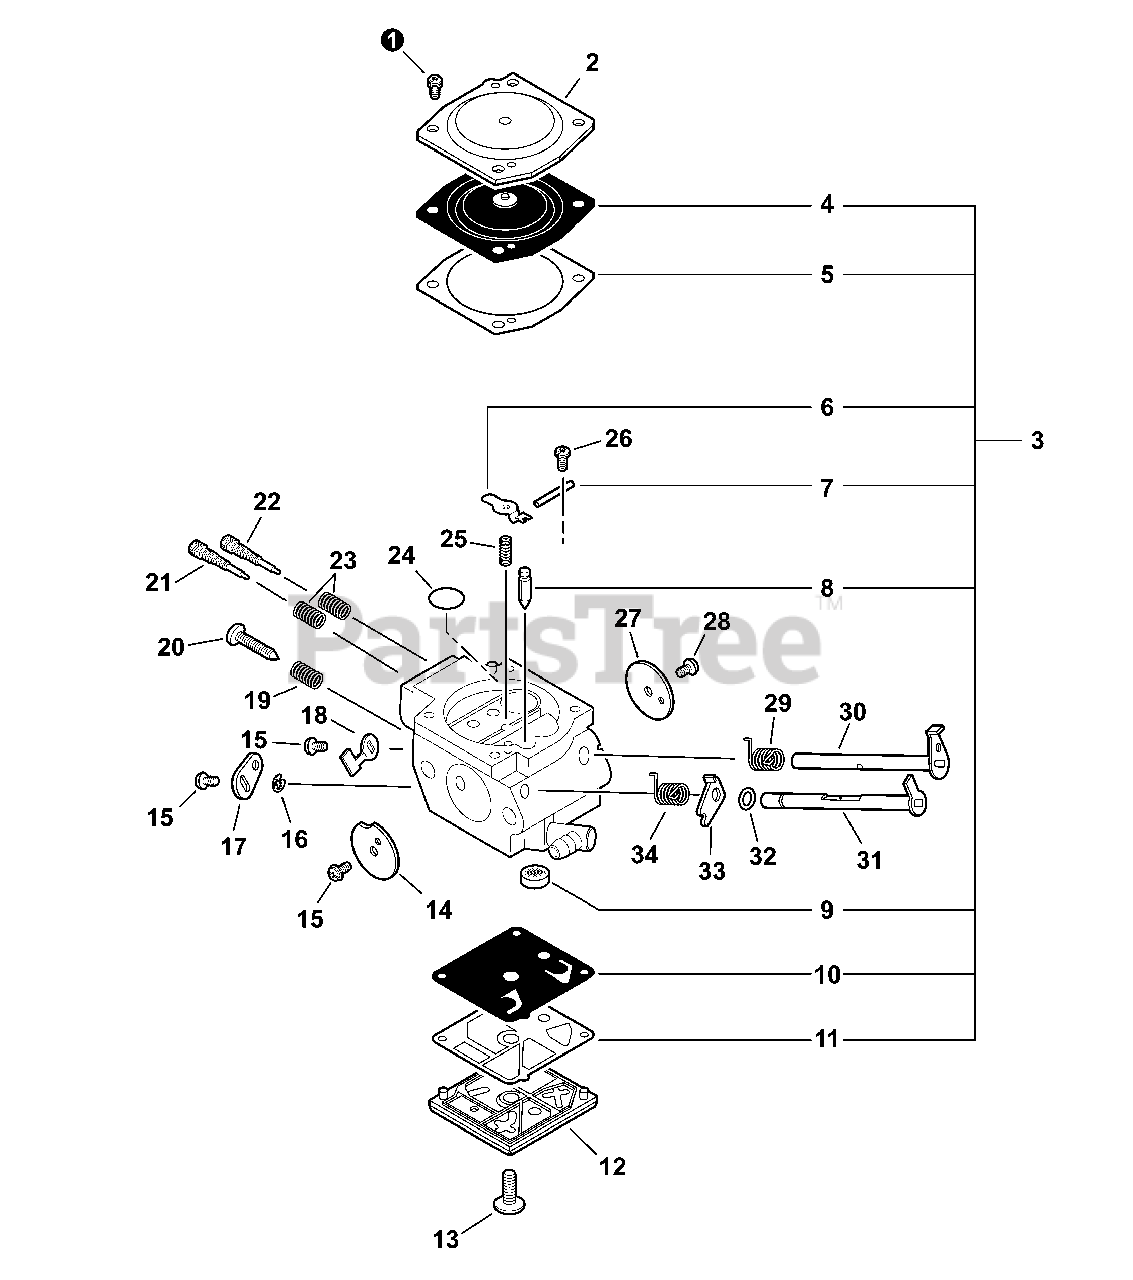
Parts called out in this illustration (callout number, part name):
2	COVER, METERING DIAPHRAGM
3	REPAIR KIT
4	DIAPHRAGM, METERING
5	GASKET, METERING
6	LEVER, METERING
7	PIN, METERING LEVER
8	VALVE, INLET NEEDLE
9	STRAINER
10	DIAPHRAGM, PUMP
11	GASKET, PUMP
12	COVER, FUEL PUMP
14	VALVE, THROTTLE
17	LEVER, CHOKE
18	STOP, THROTTLE
19	SPRING, IDLE ADJUST
20	SCREW, IDLE ADJUST
21	NEEDLE, HIGH SPEED
22	NEEDLE, LOW SPEED
23	SPRING, NEEDLE
24	PLUG, WELCH
26	SCREW, METERING LEVER PIN
27	VALVE, THROTTLE
29	SPRING, THROTTLE RETURN
30	SHAFT, THROTTLE
31	SHAFT, CHOKE
33	LEVER, FAST IDLE
34	SPRING, CHOKE RETURN
